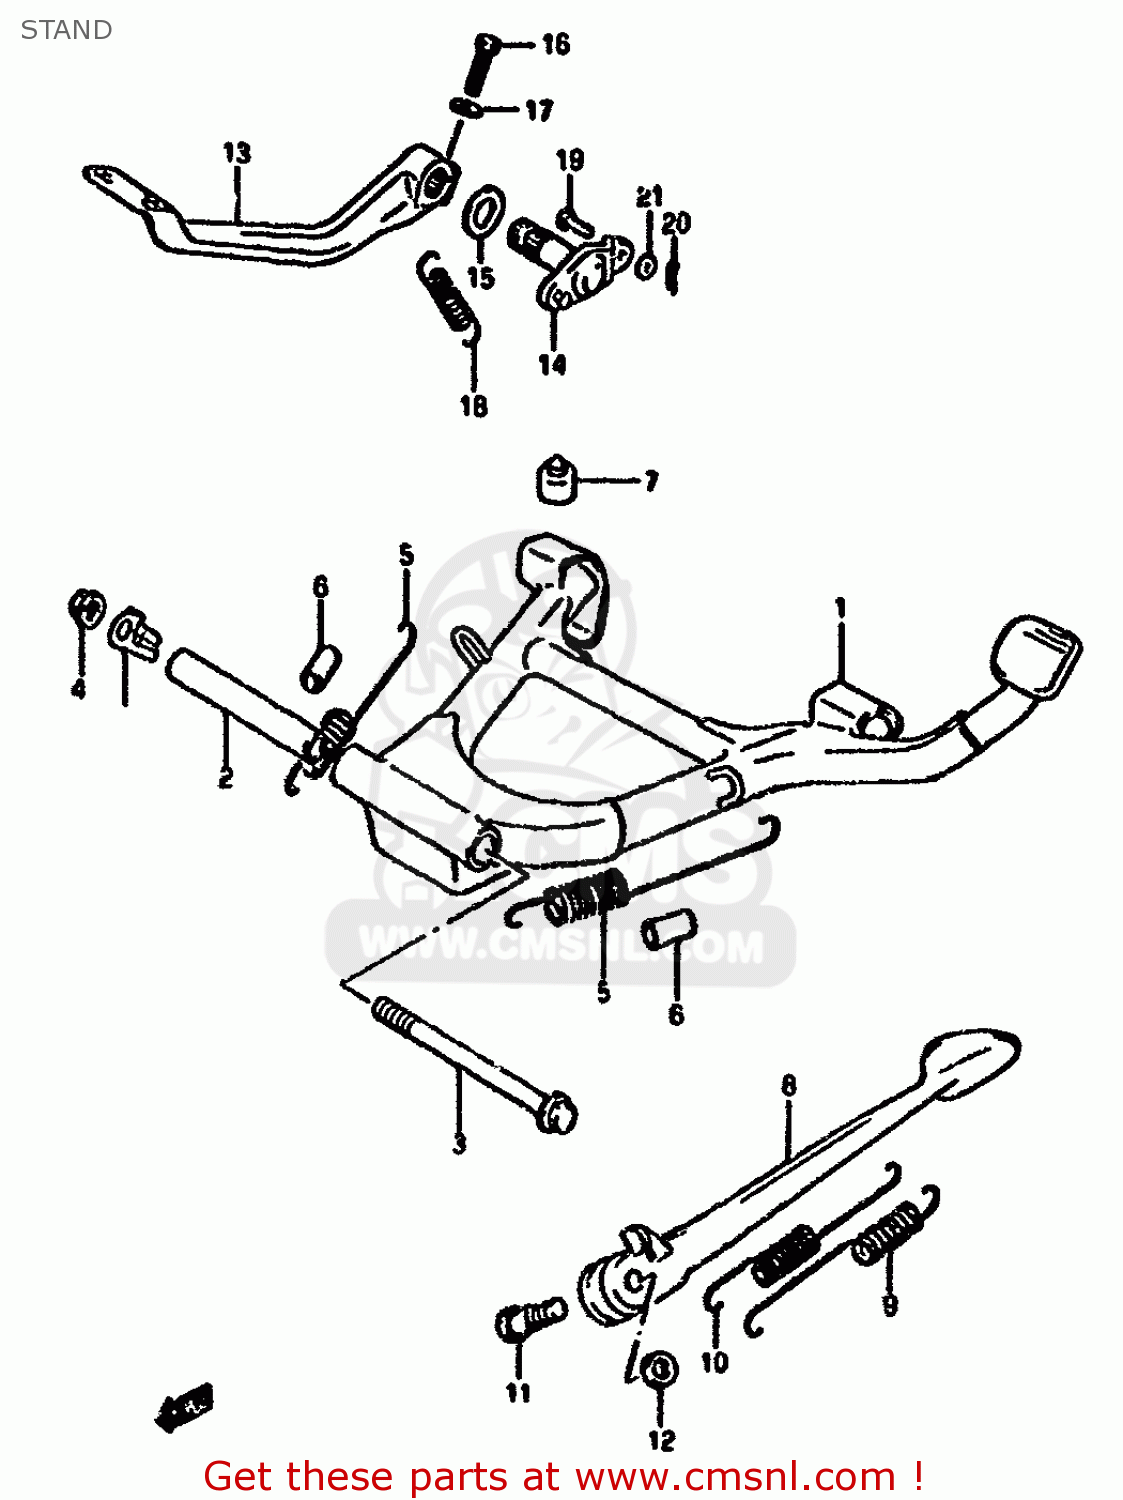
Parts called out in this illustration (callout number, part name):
1	STAND,CENTER
2	SPACER (10.5X16X102)
3	BOLT(10X132)
4	NUT
5	SPRING
6	HOSE
7	CUSHION
8	STAND,SIDE
9	SPRING
10	SPRING
11	BOLT(10X38)
12	NUT
13	PEDAL,BRAKE
14	ARM,BRAKE PEDAL
15	WASHER,BRAKE BOSS
16	BOLT
17	WASHER
18	SPRING
19	PIN
20	PIN
21	WASHER
